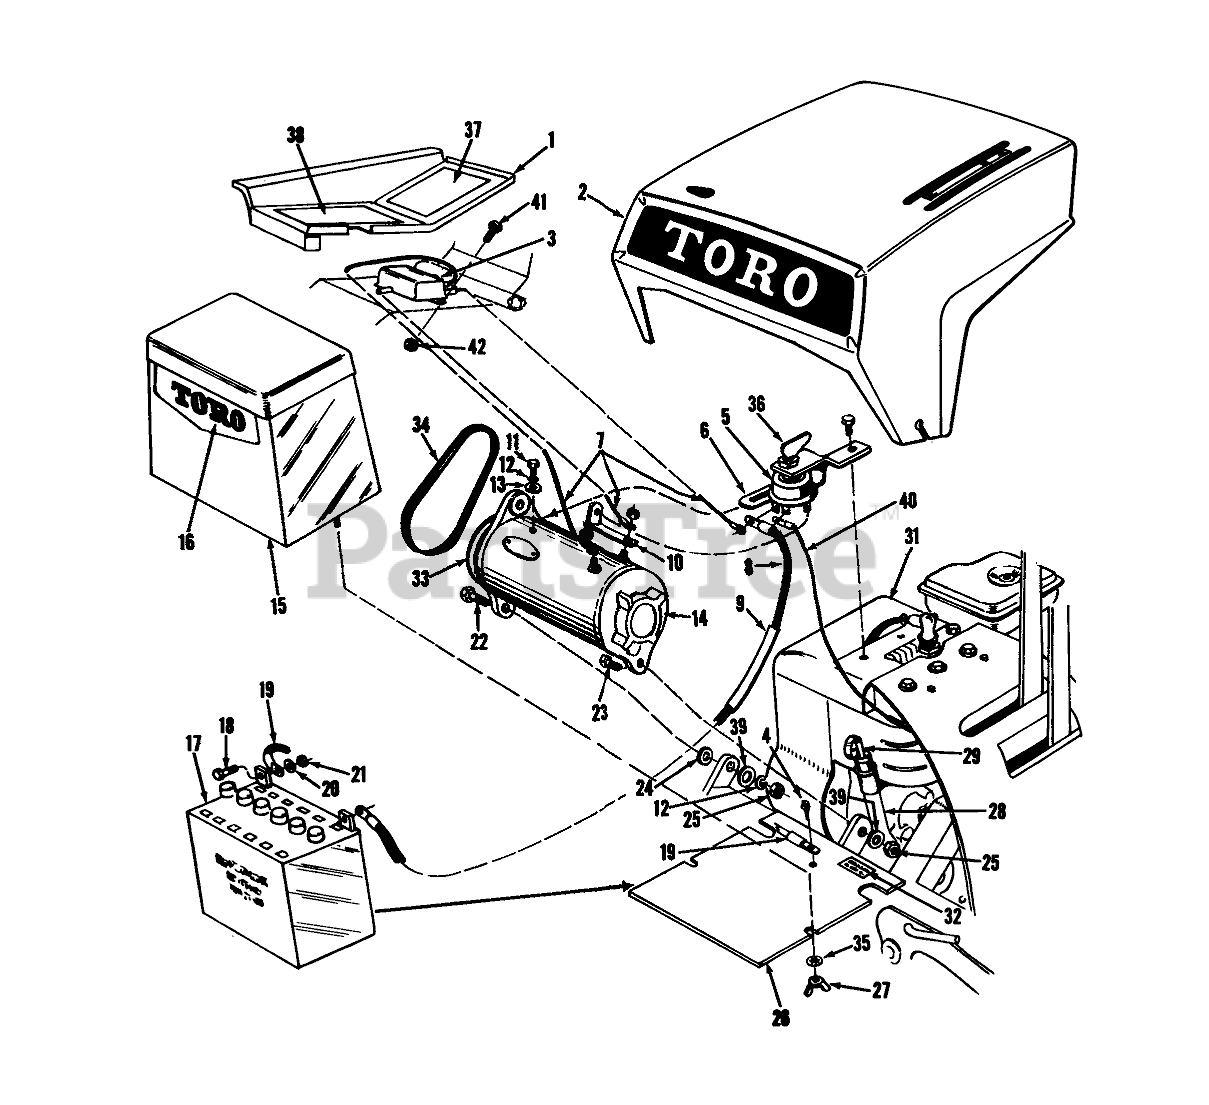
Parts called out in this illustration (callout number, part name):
1	Fender, Right Hand
3	Voltage Regulator
4	10-16 X 3/8 THDG SCREW
5	Switch
10	Bar, Ignition
11	SCREW-HH
12	WASHER-LOCK
13	WASHER-PLAIN
14	Starter-Generator
15	Case, Battery
18	SCREW-HH
20	WASHER-FLAT
21	NUT-HEX
22	SCREW-HH
23	SCREW-HH
24	WASHER-FLAT
25	NUT-HEX
26	Frame w/Bushings
27	NUT-WING
31	Engine (Electric Only)
32	NEG GROUND DECAL
34	Belt
35	WASHER-LOCK
39	WASHER-FLAT
41	SCREW-PTH
42	NUT-LOCK, NI
